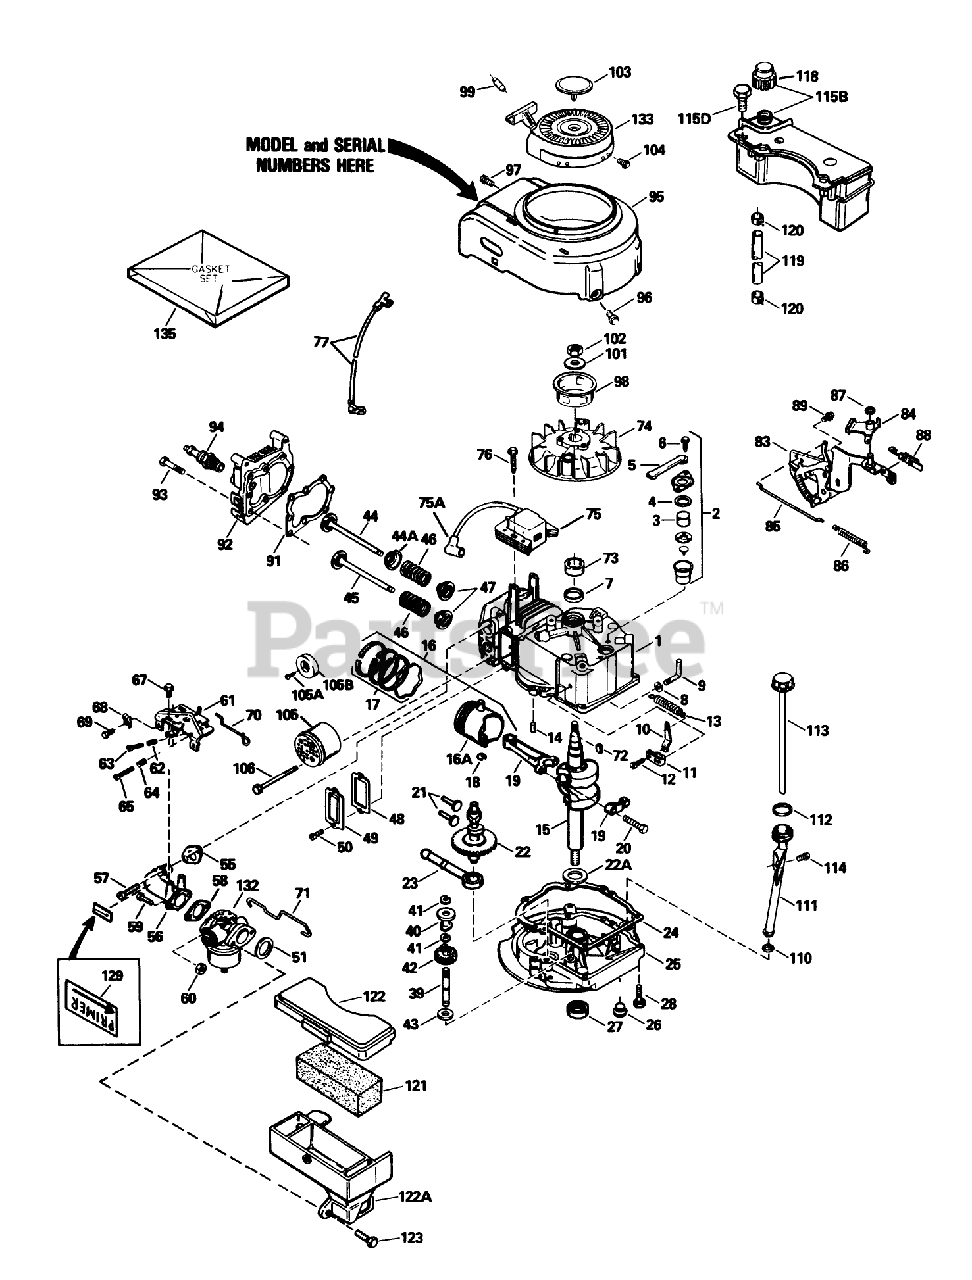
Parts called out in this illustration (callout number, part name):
1	Cylinder Assy. (Incl. #24)
2	Breather Assy. (Incl. Ref. #46 thru 51)
3	Element-Breather
4	Gasket-Breather
5	Tube, Breaker
6	Screw (10-24 x 9/16)
7	Seal-Oil
8	Washer-Flat
9	Rod, Governor (Incl. No. 36)
10	Governor Lever
11	Clamp-Lever, Governor
12	Screw
13	Spring Governor
14	Pin-Dowel
15	Crankshaft
16	Piston-Pin Ring Assy. (Std.)(Incl. Ref. #16A, 17 18)
16	Piston-Pin Ring Assembly (.010 oversize)(Incl. Ref. #16A, 17 18)
16	Piston, Pin Ring Assy. (.020 Oversize)(Incl. Ref. #13A, 14, 15)
16A	Piston Pin Assy. (Std.)(Incl. Ref. #14)
16A	Piston Pin Assembly (.010 oversize)(Incl. Ref. #18)
16A	Piston Pin Assy. (.020 Oversize) (Incl. Ref. #14)
17	Ring Set-Piston (Std.)
17	Ring Set, Piston(.0100versize)
17	Ring Set (.020" OS)
18	Ring-Retaining, Piston Pin
19	Rod Assy., Connecting (Incl. Ref. #17)
20	Bolt-Rod, Connecting
21	Lifter-Valve
22	Camshaft (Mech.Compression Release)
22A	Washer-Thrust
23	Oil Pump ASM
24	Gasket
25	Flange-Mounting (Incl. Ref. #26, 27 39)
26	Plug Oil Drain
27	Seal-Oil
28	Screw (1/4-20 x 1-1/4)
39	Shaft-Governor
40	Spool-Governor
41	Ring-Retaining
42	Governor Gear ASM
43	Washer
44	Valve, Intake (Std.) (Incl. Ref. #40)
44	Valve, Intake (1/32" oversize)(Incl. No. 40)
44A	Seal Assy., Intake
45	Valve, Exhaust (Std.)(Incl. No. 40)
45	Valve, Intake (1/32" oversize)(Incl. No. 40)
46	Spring-Valve
47	Cap-Valve, Spring
48	Gasket-Cover, Valve
49	Cover-Valve
50	Screw
51	Gasket-Cleaner, Air
55	Gasket-Intake Pipe
56	Pipe-Intake (Incl. Ref. #59)
57	Screw (1/4-20 x 1)
58	Gasket
60	Nut and Lock Washer (1/4-28)
61	Control Assy.-Remote Speed (Incl. Ref. #69 thru 72 76)
62	61709/GIL1515A/95-5
63	Screw
64	Spring-Compression
65	Screw
67	Screw (10-24 x 9/16)
68	Conduit
69	Screw (10-32 x 3/8)
70	2035A67 ADD.ASSEMBL
71	Link-Throttle
72	Key-Flywheel
73	Spacer
74	Flywheel
75	Solid State
75A	Cover-Spark Plug
76	Screw
77	Ground Wire
83	Bracket-S.E. Brake
84	Lever-Brake
85	Link-Control
86	Spring-Extension
87	Ring-Retaining
88	Terminal
89	Screw (1/4-20 x 3/8)
91	Gasket-Cylinder Head
92	Head-Cylinder
93	Screw (5/16-18x1-1/2)
94	Spark Plug-Resistor (R J19 L M)
95	Housing-Blower
96	Screw (1/4-20 x 1/2)
97	Screw (10-24 x 9/16)
98	Hub-Starter
99	Retainer-Starter Rope
101	Washer-Belleville
102	Nut-Flywheel
103	Plug Starter
104	Screw, Hex Hd.
105	Muffler Assembly (Incl. Ref. #106)
105A	Cover-Muffler
105B	Screw (8-32 x 3/8)
106	Screw
110	Gasket
111	Oil Fill Tube
112	O-Ring
113	Dipstick
114	Screw (10-32 x 1/2)
115B	Tank Assembly-Fuel (Incl. Ref. #102)
115D	Screw (10-32 x 35/64)
118	Cap-Fuel
119	Line-Fuel
120	Clamp-Line, Fuel
121	Filter-Air Cleaner
122	Cover-Air Cleaner
122A	Body Air cleaner
123	Screw
129	Decal-Primer
132	Carburetor (Incl. Ref. #83)
133	Starter-Rewind
135	Gasket Set (Incl. Items Marked *)
